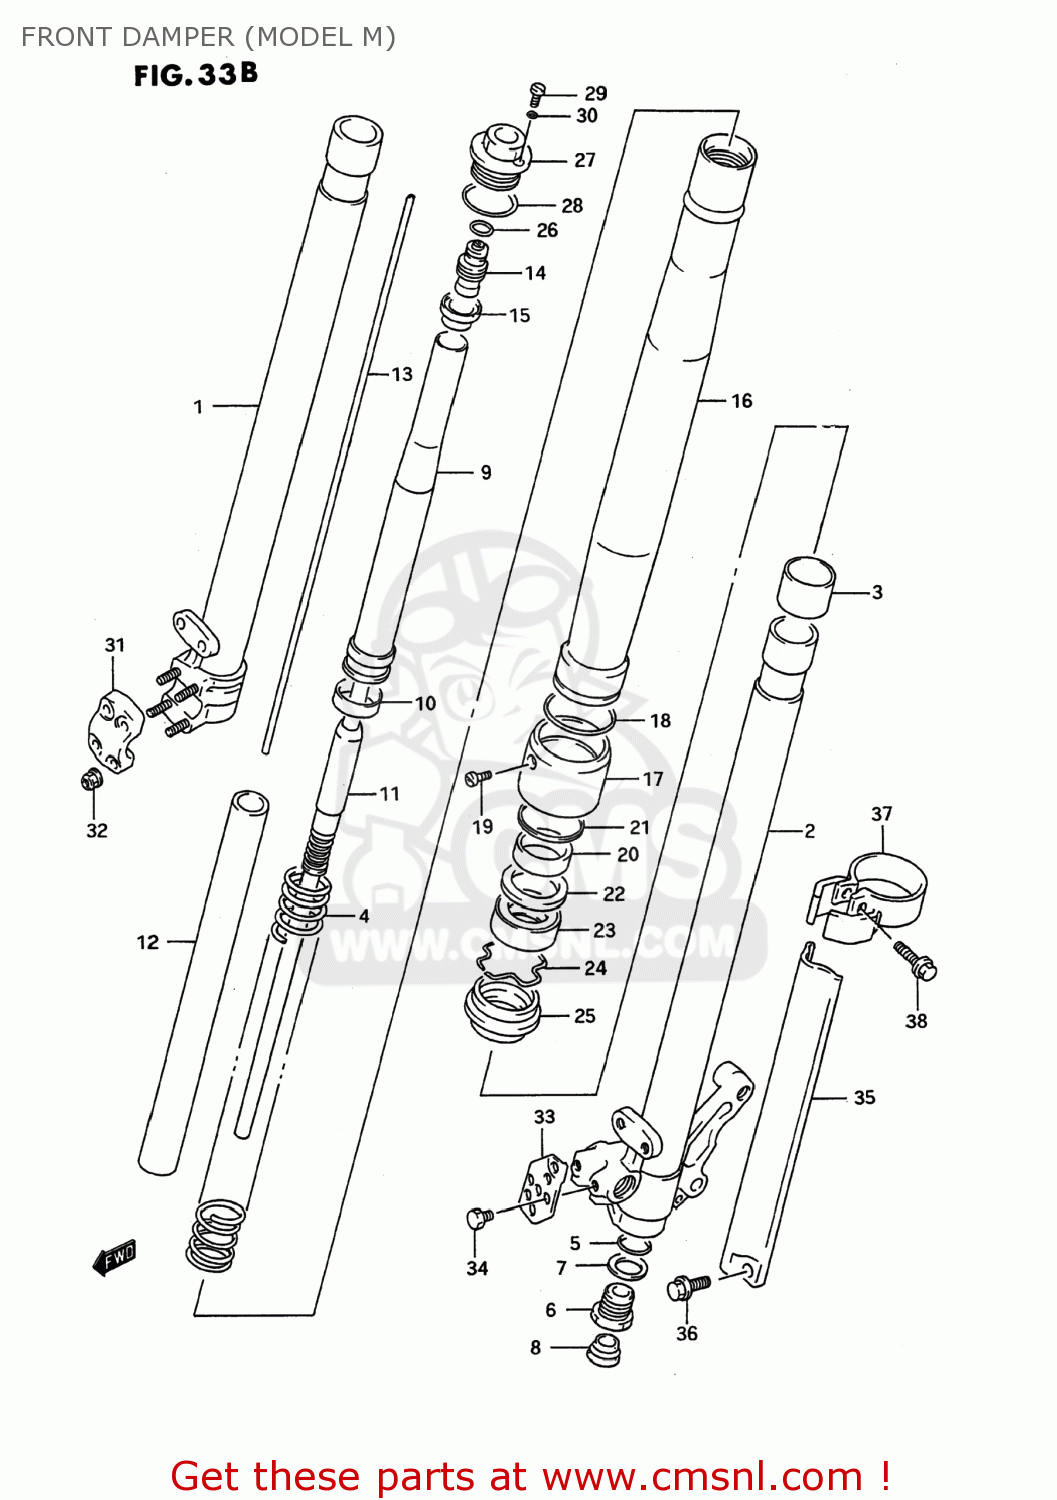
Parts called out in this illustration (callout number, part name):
1	TUBE,INNER,RIGHT
2	TUBE,INNER,LEFT
3	BUSH,SLIDE
4	SPRING,MAIN
5	O-RING
6	BOLT,CENTER
7	GASKET (NAS)
8	CAP
9	SPACER,SPRING
10	RING,PISTON
11	ROD ASSEMBLY,PISTON
12	CYLINDER
13	ROD,PUSH
14	ADJUSTER,SPRING
15	SEAT,SPRING STOPPER
16	TUBE,OUTER
17	CASE,OIL SEAL
18	O RING,CASE
19	SCREW
20	BUSH,GUIDE
21	RING,STOPPER,UPPER
22	SPACER,SEAL
23	OIL SEAL,FRONT FORK
24	RING,OIL SEAL STOPPER
25	SEAL,DUST
26	NUT
27	BOLT,FORK
28	O RING
29	BOLT,PLUG
30	O RING, PLUG
31	HOLDER,AXLE,R
32	NUT
33	CLAMP,FRONT BRAKE HOSE
34	BOLT, HOSE GUIDE
35	PROTECTOR,FORK,L
36	BOLT,PROTECTOR(6X10)
37	GUIDE,FORK PROTECTOR,R
38	BOLT,PROTECTOR GUIDE
